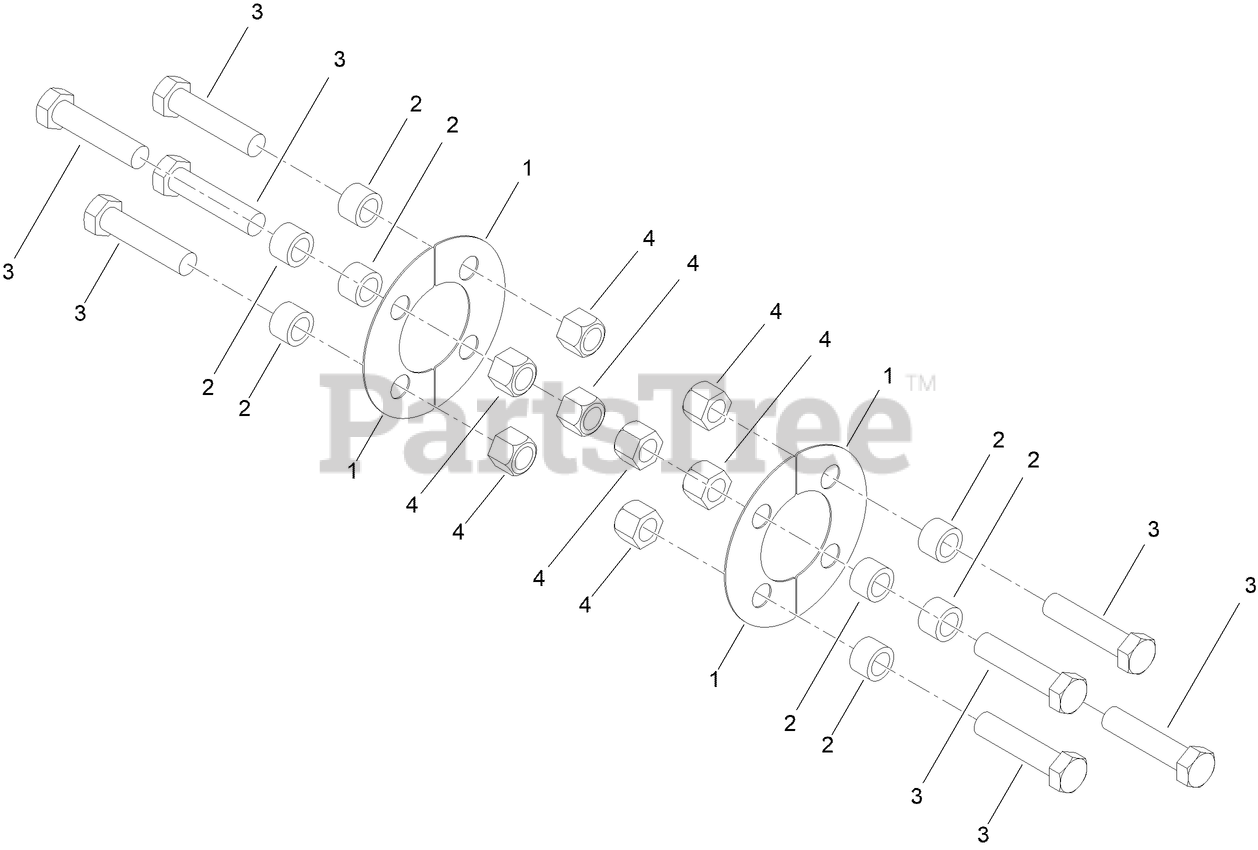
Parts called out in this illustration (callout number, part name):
1	PLATE-SHIM,HUB,
2	SPACER-CLEVIS
3	SCREW-HH
4	NUT-HEX
